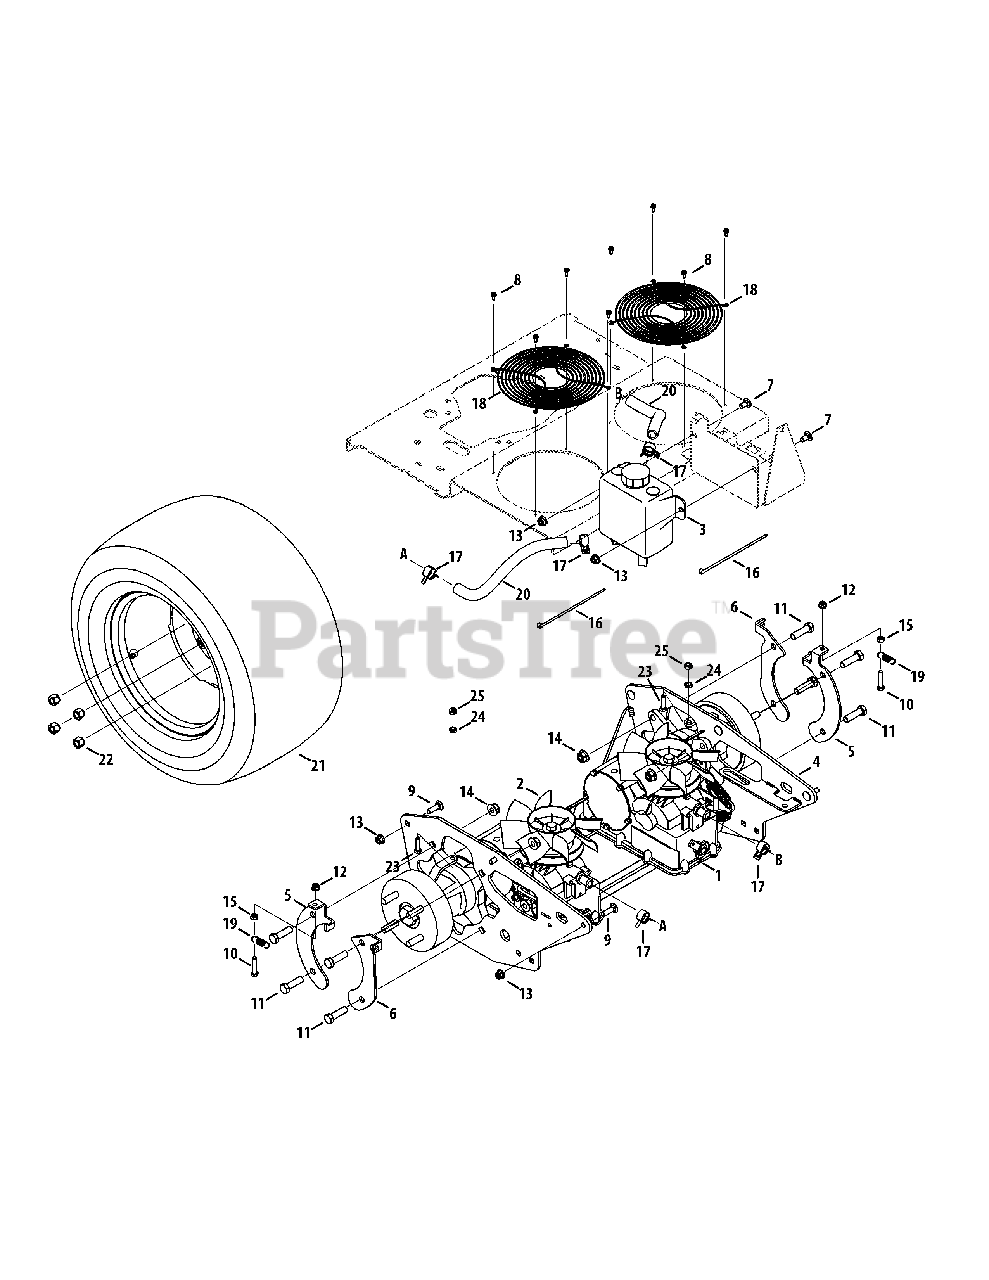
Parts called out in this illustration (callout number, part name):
1	Transmission, LH
2	Transmission, RH
3	Hydro Tank Assembly
4	Transmission Bracket Assembly
5	Spring Brake Mounting Bracket
6	Brake Cable Mounting Bracket
7	Carriage Bolt, 3/8-16 x .75
8	Screw, 10-24 x .500
9	Carriage Bolt, 3/8-16 x 1.25
10	Hex Cap Screw, 5/16-18 x 1.50
11	Hex Cap Screw, 1/2-13 x 1.75
12	Nut, 5/16-18, Flangelock
13	Nut, 3/8-16, Flangelock
14	Nut, 1/2-13, Flangelock
15	Nut, 5/16-18, Hex
16	Cable Tie
17	Hose Clamp, .9375
19	Extension Spring, .50 OD x 1.71
20	Hose, 5/8 ID x 12.00 LG
21	Wheel Assembly, 24 x 12-12
22	Lug Nut, 1/2-13
23	Hex Cap Screw, 5/16-18 x 1.00
24	Jam Nut, 5/16-18
25	Hex Lock Nut, 5/16-18
